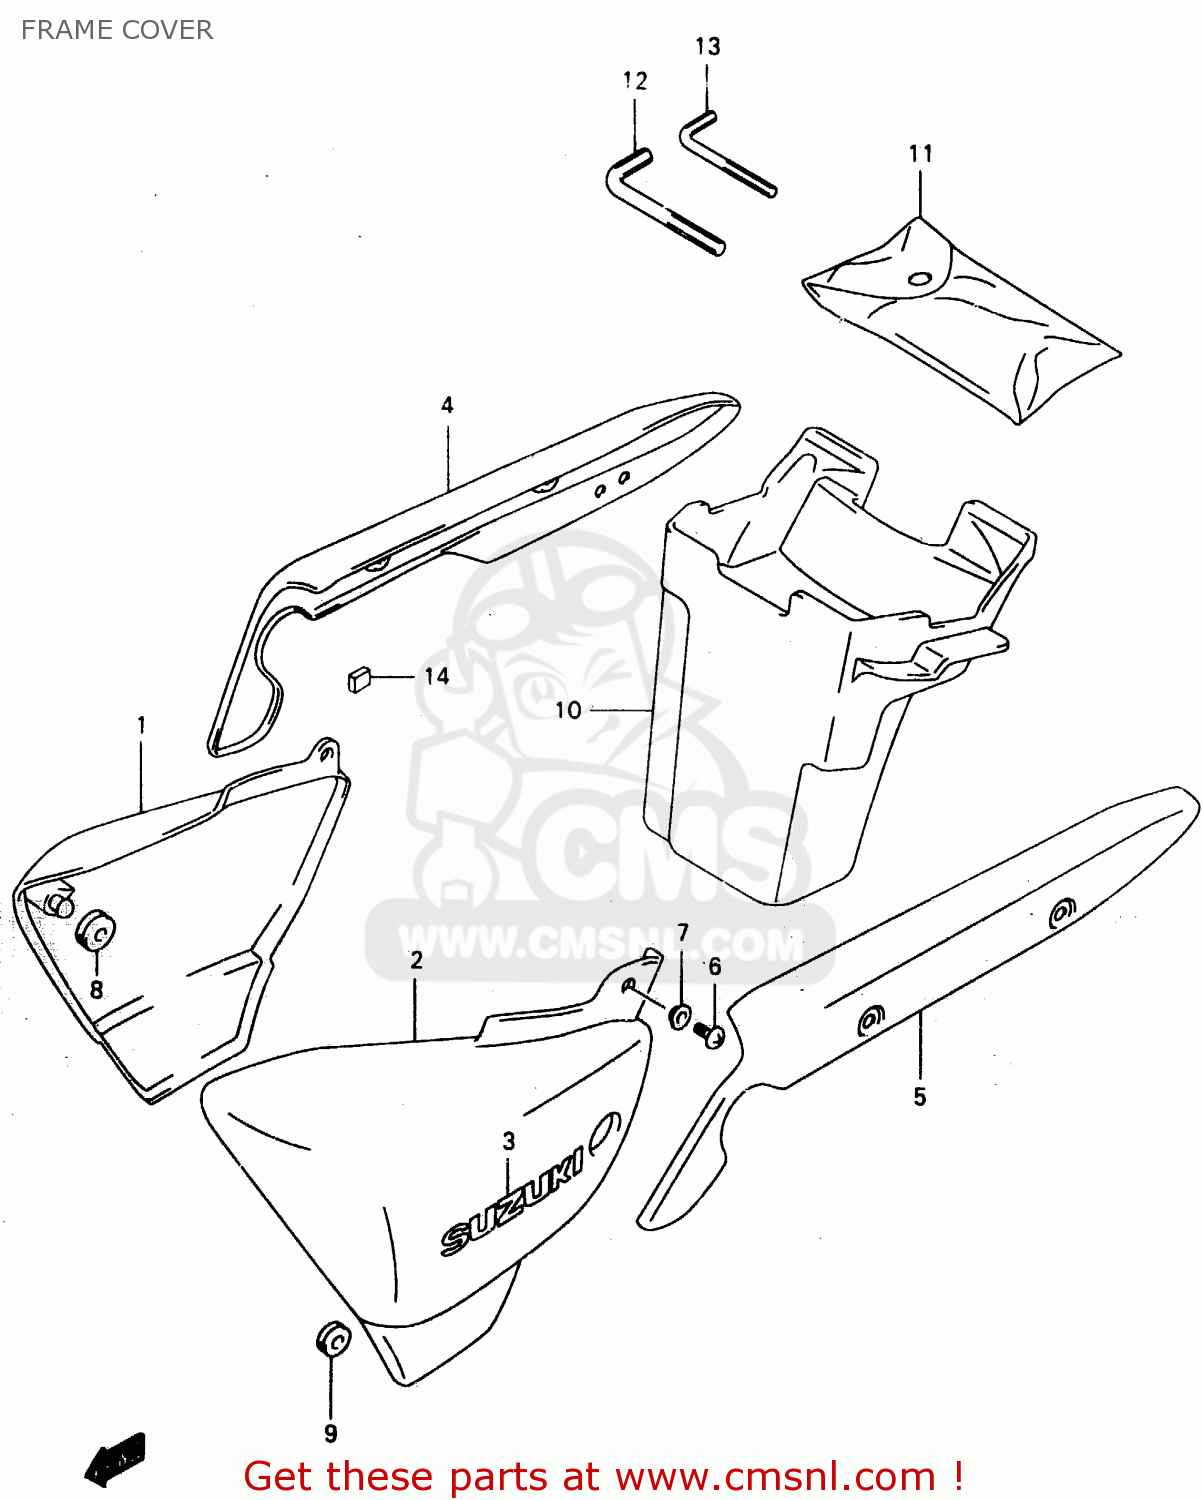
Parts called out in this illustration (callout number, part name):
1	COVER,FRAME,RIGHT
2	COVER,FRAME,LEFT
3	EMBLEM,FRAME COVER
4	COVER,FRAME RR,R
5	COVER,FRAME RR,L
6	SCREW 6X12
7	WASHER
8	CUSHION
9	CUSHION
10	BODY,LUGGAGE BOX
11	TOOL ASSY
12	SPANNER,HEXAGON(6)
13	SPANNER,HEXAGON(4)
14	CUSHION
